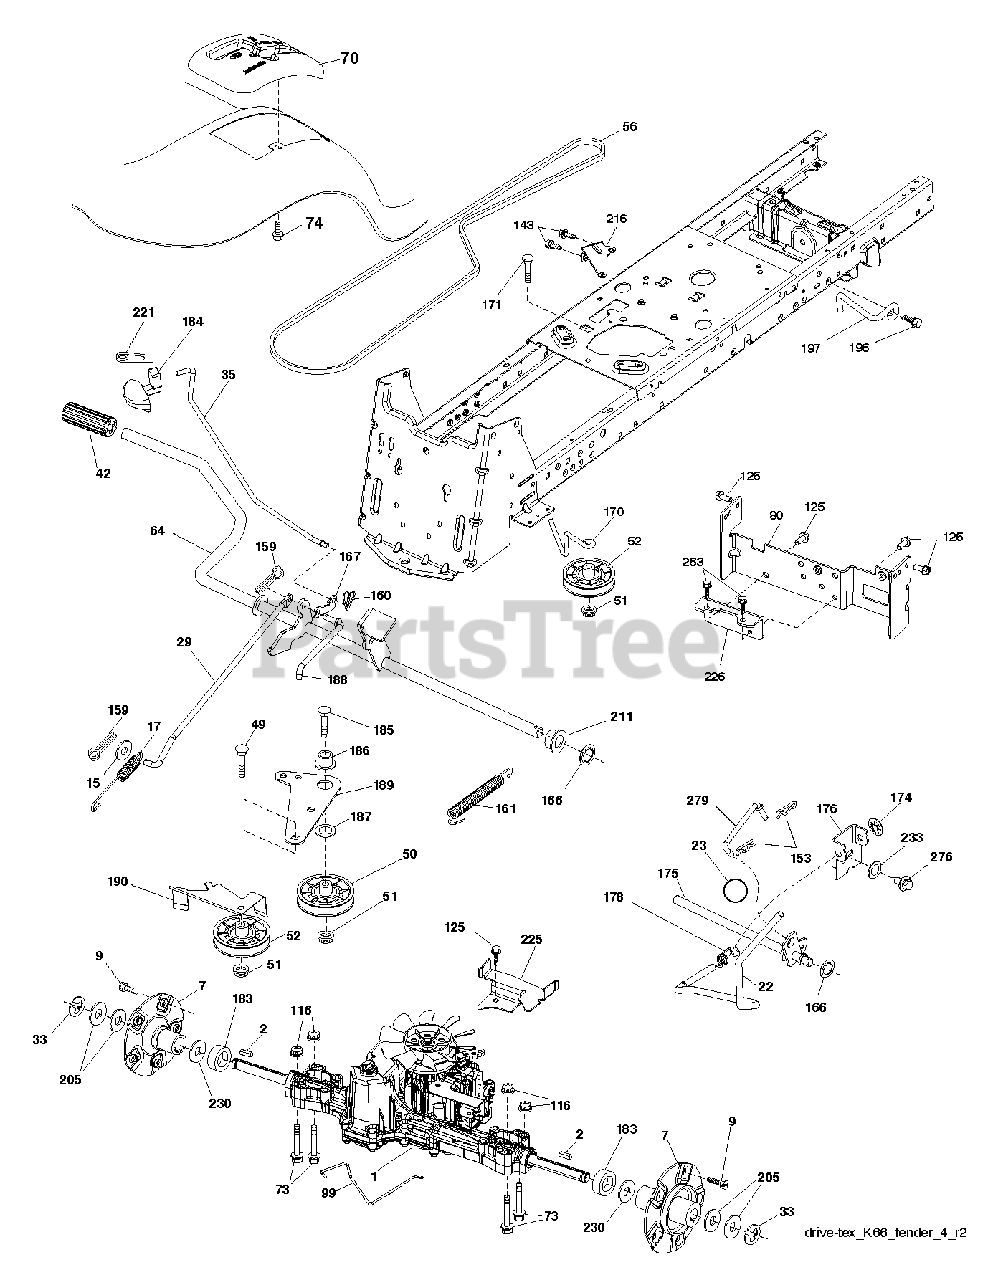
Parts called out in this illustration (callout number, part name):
2	KEY 1/4 X 2.5
7	HUB.ASM.WHEEL.REAR.23"TEX
9	HUB BOLT
17	SPRING.BRAKE.K46
22	ROD.SHIFT.FENDER.STGT.
23	KNOB.DELUXE.(PISTOL.GRIP).BLAC
29	ROD.BRAKE.K66
33	E RING HYT
35	ROD.BRAKE.PARKING.LT.T
49	BOLT
50	IDLER.FLAT.910.OFFSET
51	NUT LOCK FLG 3/8-16 UNC
52	IDLER.V-GROOVE.910.OFFSET
64	SHAFT.ASM.PEDAL.BRAKE.
70	PAD.FOOTREST.RH.STGT.BLACK
73	BOLT HEX 5/16-18 GR 5
74	SCREW.HI-LO.CONSOLE
80	STRAP.TORQUE.K66
99	ROD.SPRING.BYPASS.K66.GT.Z
116	NUT LOCK HEX FLANGE 5/16-18
125	SCREW
143	SCREW LT
159	COTTER PIN
160	RETAINER CLIP
161	SPRING, RETURN LT
166	NUT.PUSH.625
167	LATCH.BRAKE.SPRING
170	KEEPER.V-IDLER.CENTER.
171	BOLT
174	NUT.PUSH.500.2006
175	SHAFT.ASM.SHFT.T2.TLT
176	ARM.CLEVIS.ROD.SHIFT
178	SPRING.SHIFT.GT2006
183	SPACER.AXLE.HG.TEX
184	HANDLE.PARKG.BRK.HUSQ/PRED.667
186	SPACER.RETAINER
187	WASHER 12/32X2X10GA
188	LINK.CLUTCH.GROUND.DRIVE
189	BELLCRANK.GROUND.DRIVE.TEX.
190	KEEPER.BELLCRANK.DRIVE
196	SCREW 3/8-16X1
197	BRKT.ANIT-ROTATION.CLUTCH
211	BUSHING.SHAFT.BRAKE.HAND
216	BRACKET.PULLEY.IDLER.W/TEX
221	RETAINER.SPRING.CLIP.H
225	KEEPER.BELT.TRANSAXLE.K66
226	BRACKET.MOUNT.TORQUE.K66.TG
230	WASHER T
233	WASHER SERRATED
263	SCREW, 3/8-16X3/4
276	BOLT FIN HEX 7/16-14 X 1
279	1INK.ASM.SHIFT.FENDER.K66
